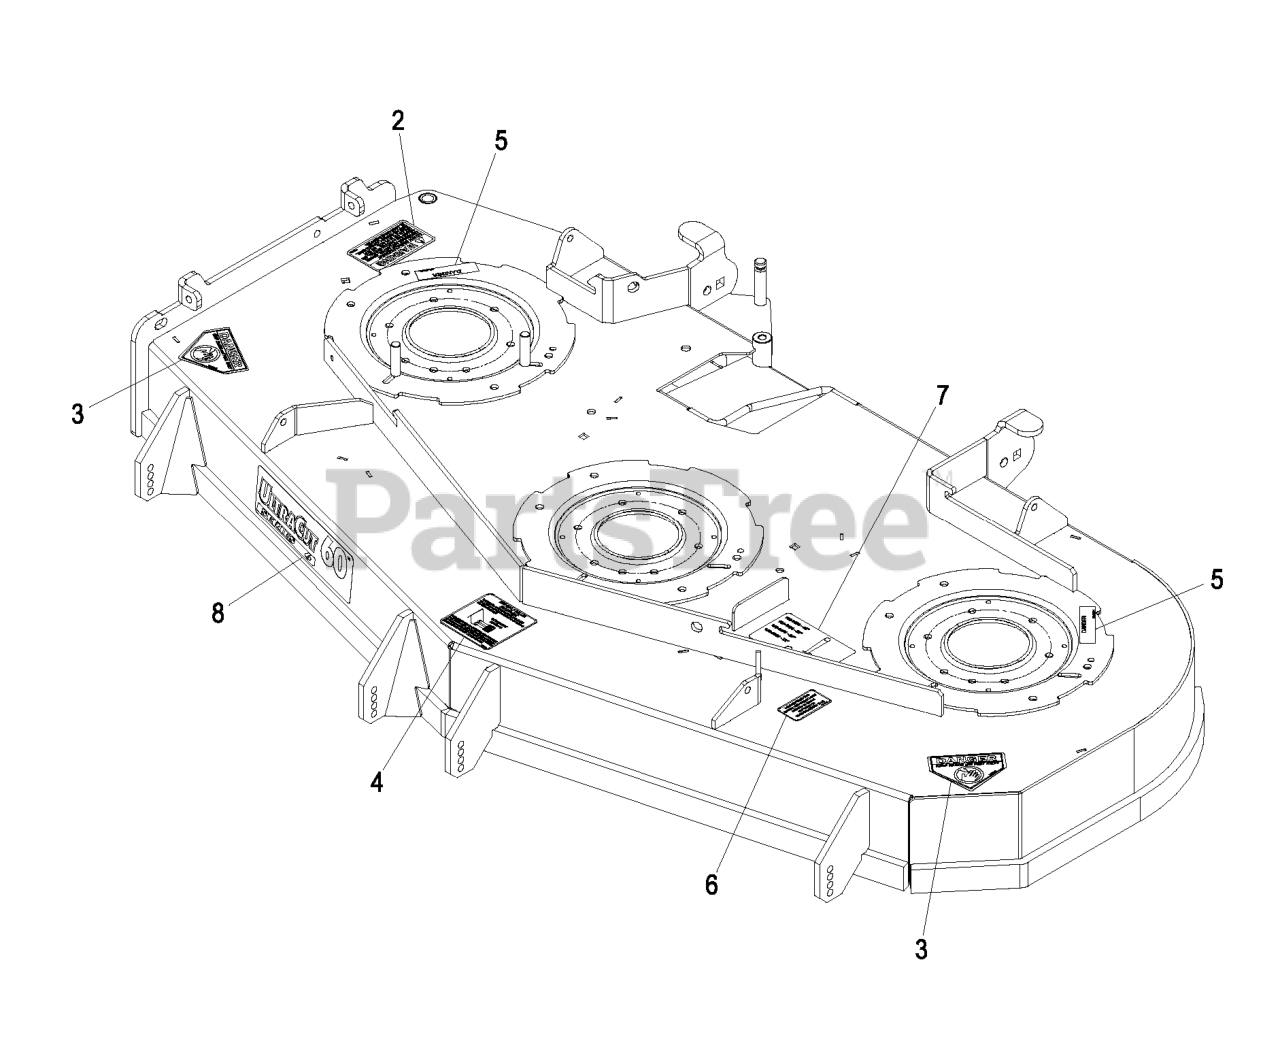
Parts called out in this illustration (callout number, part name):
2	DECAL-WARNING, DISCHARGE
3	DECAL-DANGER
4	DECAL,ANTISCALP
5	DECAL-COVER, MISSING
6	DECAL,BOLT TORQUE
7	DECAL,BELT ROUTING
8	DECAL,ULTRACUT 60 SERIES
